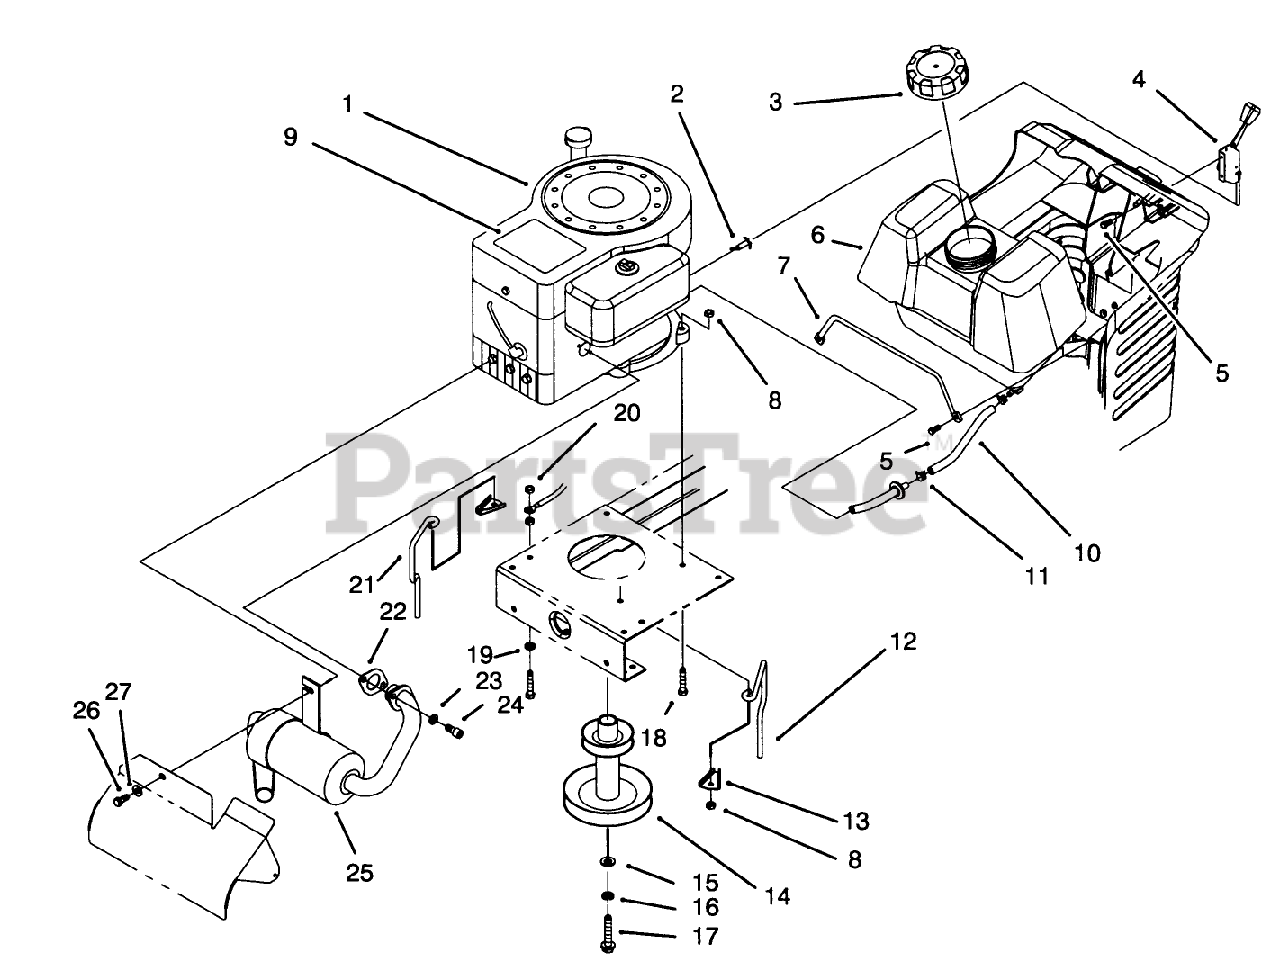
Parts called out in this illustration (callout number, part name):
1	Engine-13 H.P
2	THROTTLE CABLE ASM
3	GAS CAP ASM
4	THROTTLE CONTROL ASM
5	SCREW-SPECIAL
6	GAS TANK ASM
7	GAS TANK ROD
8	NUT-LOCK, NI
11	CLAMP-HOSE
12	LH BELT GUIDE
13	ANCHOR-GUIDE, BELT
14	ENGINE PULLEY
15	WASHER-FLAT
16	WASHER-LOCK
17	SCREW-HH
18	SCREW-HH
19	WASHER-LOCK
20	NUT-KEPS
21	RH BELT GUIDE
22	GASKET-EXHAUST
23	WASHER-LOCK
24	SCREW-HSH
25	MUFFLER
26	SCREW-HH
27	WASHER-LOCK
